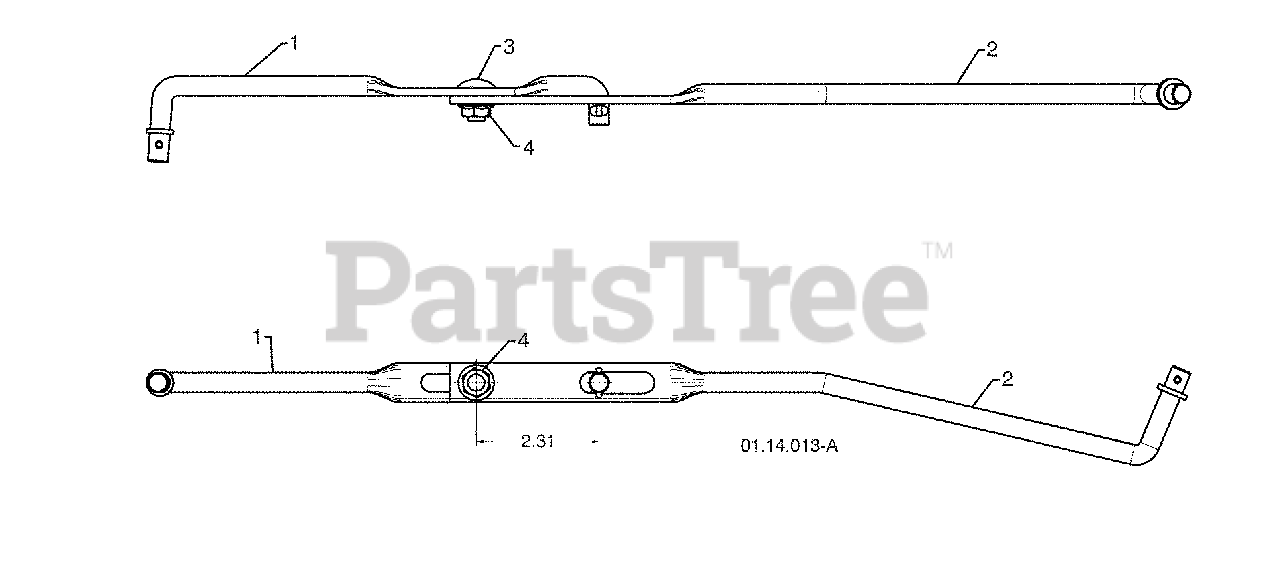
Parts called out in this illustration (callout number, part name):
1	SHIFTER ROD TOP
2	SHIFTER ROD BOTTOM
3	CARRIAGE BOLT 5/16-18 X .75
4	NUT 5/16-18
